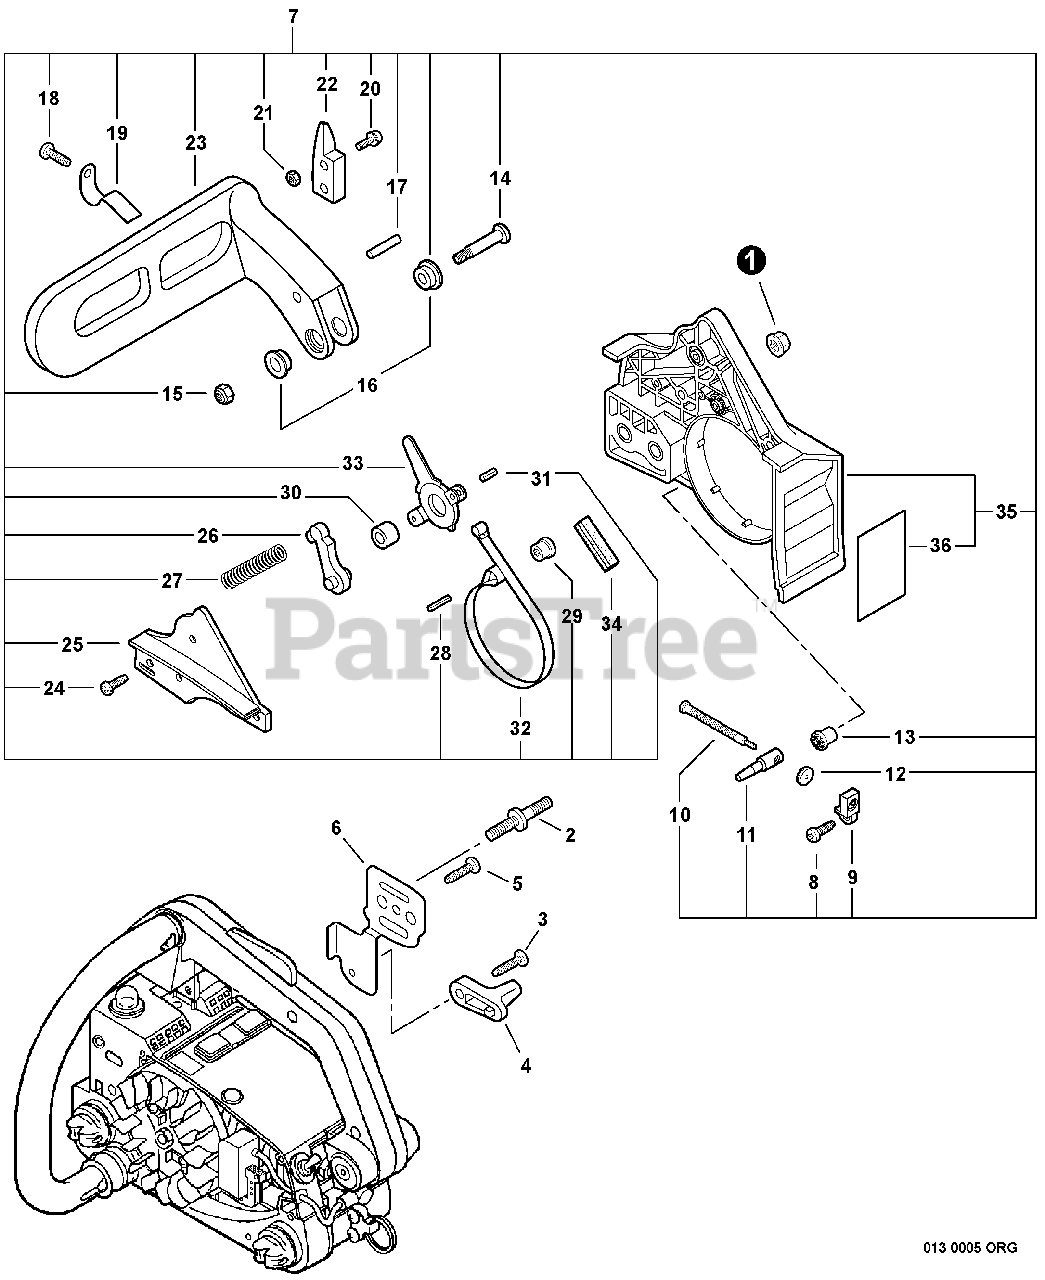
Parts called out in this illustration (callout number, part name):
1	CHAIN BRAKE ASSY
2	SCREW 4×12
3	COVER, BRAKE
4	SPACER 8×12×9
5	SPRING, COMPRESSION
6	STOPPER, BRAKE
7	LEVER, BRAKE
8	PIN, SPRING 4×8.8
9	PIN, SPRING 2.5×12
10	BAND, BRAKE
11	SEAL, BRAKE
12	ADJUSTER, BRAKE
13	ROLLER 4×23.8
14	SCREW 4×10
15	SPRING, FLAT
16	LEVER, BRAKE
18	WEIGHT, BRAKE
19	SCREW 4×20
20	SCREW 5×32
21	COLLAR 5.3×10×13×L5
22	NUT, LOCK M5
23	GUARD, SPROCKET - ORANGE
24	SHIELD, HEAT 35×60×0.10
26	TENSIONER, CHAIN
27	GEAR, BEVEL
28	GEAR, BEVEL
29	COLLAR 8
30	SCREW 4×12
31	NUT, FLANGE M6
32	BOLT, STUD 6
33	CHAIN CATCHER
34	SCREW, TAPPING 5×20
35	SCREW 4×10
36	PLATE, GUIDE
